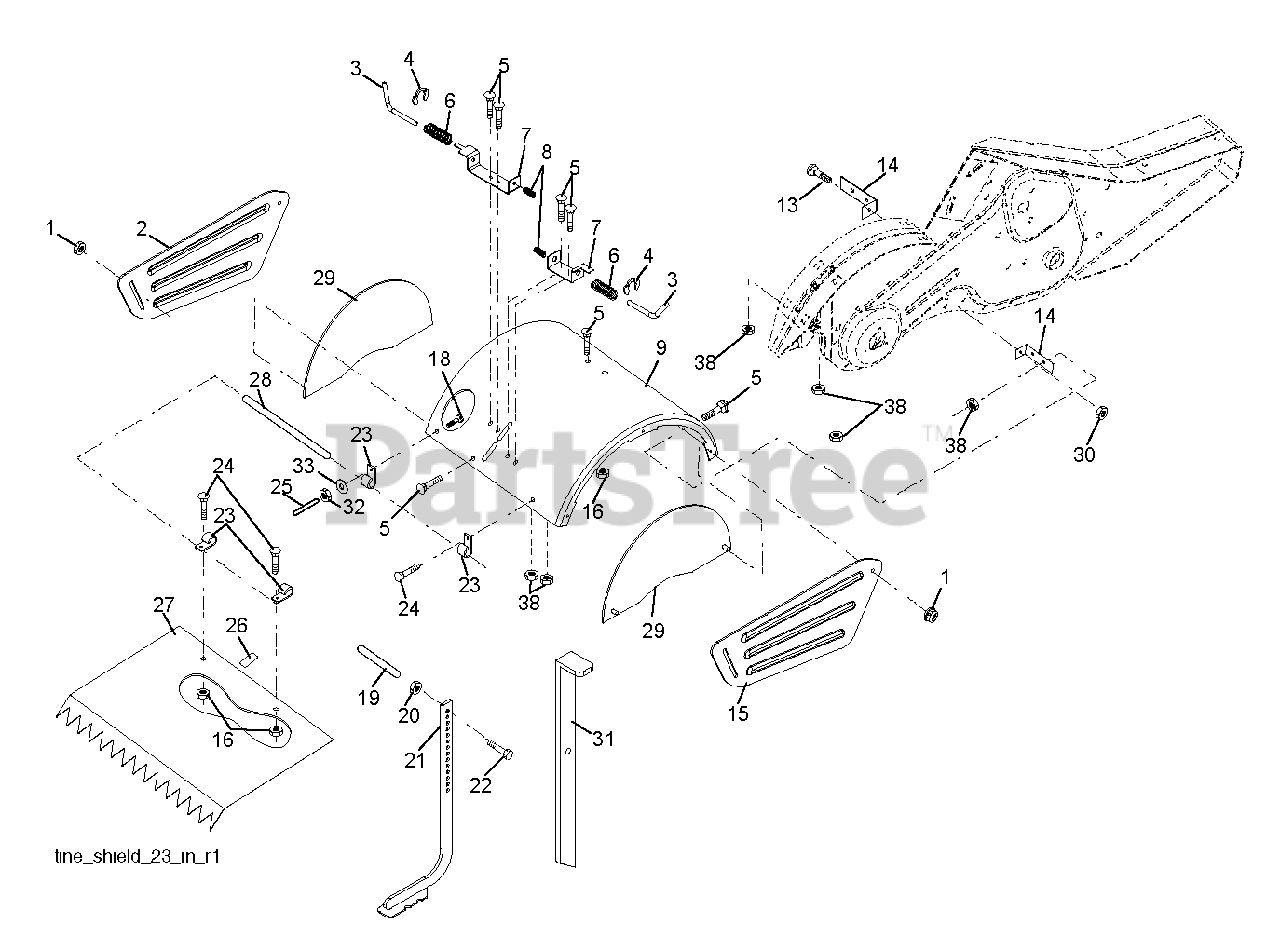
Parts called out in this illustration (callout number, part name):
1	NUT LOCK HEX FLANGE 5/16-18
2	SHIELD.PNT.SIDE.OUTER.LH.ORANG
3	STAKE PIN TI
4	RING, KLIP
5	BOLT, RDHD SQNK 5/16-18 X 3/4
7	BRACKET.LATCH.STAKE.3.20.BLACK
8	SPRING CRT
9	SHIELD.TINE.DRT17.TILLER.ORANG
13	BOLT.CARRIAGE.5/16-18
14	BRACKET.TINE.SHIELD.TILLER
15	SHIELD.SIDE OUTER.RH.ORANGE
16	NUT T
20	NUT.HEX.3/8-16UNC
21	STAKE.DEPTH.16.CRT.BLACK
22	BOLT.375-16
24	BOLT
26	PAD IDLER TI
27	SHIELD.LEVELING.17".ORANGE
28	PIN.HINGE.TILLER
29	SHIELD.TINE.SIDE.ORANGE.TILLER
30	LOCKNUT-FLANGE 5/16-18
31	RP.STAKE.DEPTH.DRAG.TILLR.GREY
32	NUT
33	LOCKWASHER
38	NUT
